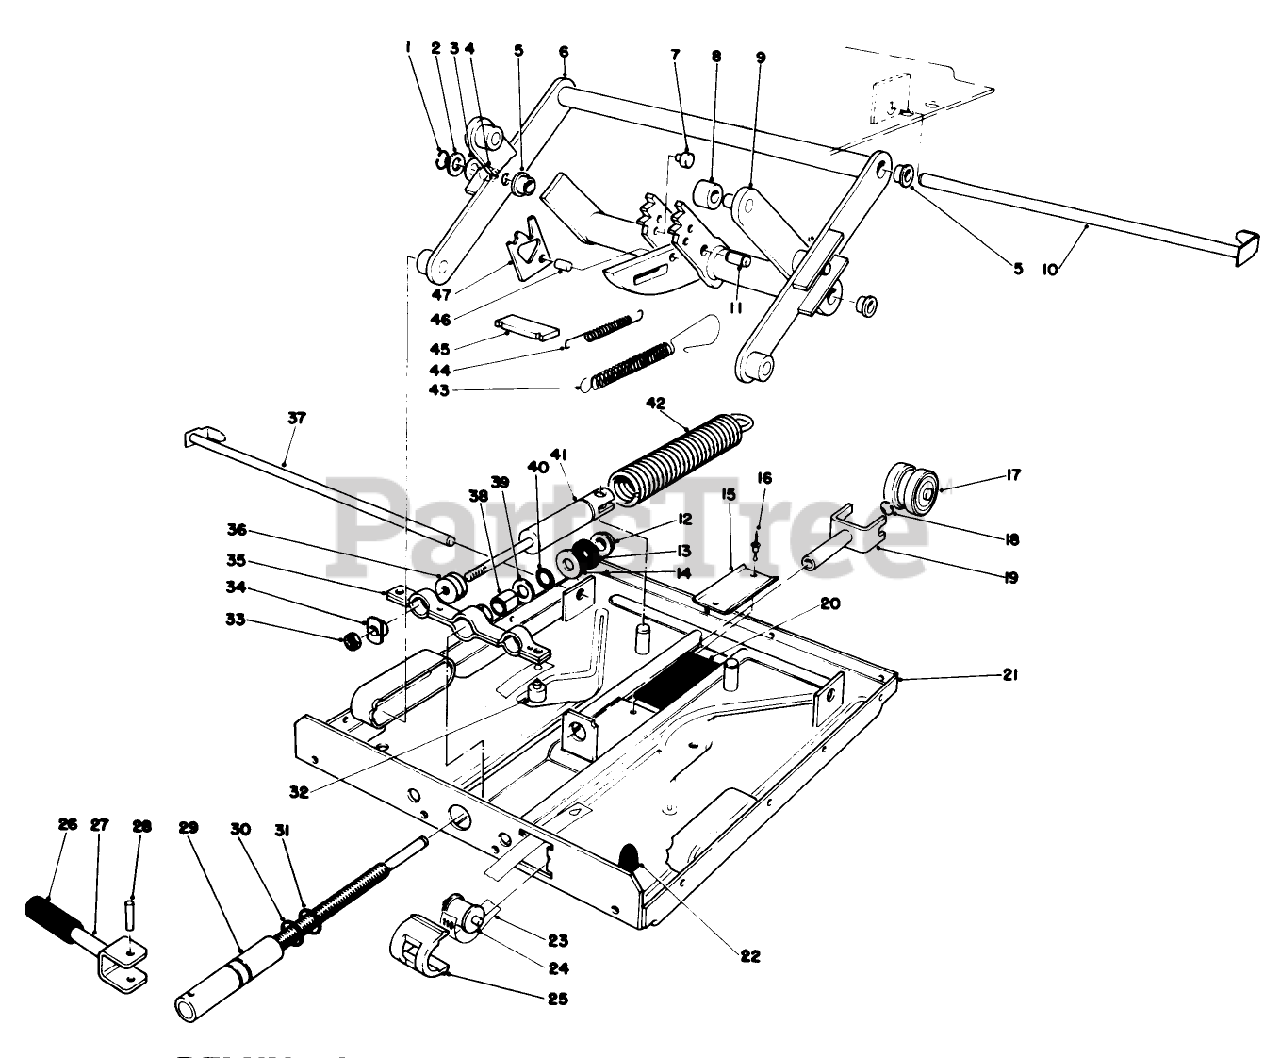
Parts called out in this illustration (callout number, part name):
1	WASHER
2	WASHER
3	WASHER
4	BRG BSHG
5	BEARING
6	Swing Arm-Outside
8	ROLLER
9	Frame Bag
11	Grooved Locking Pin 08X16CM
12	SLEEVE
13	WASHER-RUBBER
14	WASHER
15	U-TRACK
16	RIVET
17	TRIBLE BRG
18	RET RING
20	RUBBER
21	Lower Suspension Plate-Complete (Incl. Ref. #15-16 & 20)
22	BUMPER
23	WEIGHT INDICATOR BAND
24	ROLLER
25	GUIDE-SLEEVE
26	HANDLE
27	TOGGLE
28	GROOVED PIN
30	RUBBER RING 14MM BLK
31	RUBBER RING 14MM RED
34	WELD NUT
35	Spring Bracket
36	THREADED ROD
38	SLEEVE
39	WASHER
40	BEARING-THRUST, NEEDLE
41	SHOCK ABSORBER
42	COIL SPRING
43	SPRING-COIL
44	SPRING-COIL
45	PLATE
47	BRACKET-RELEASE
